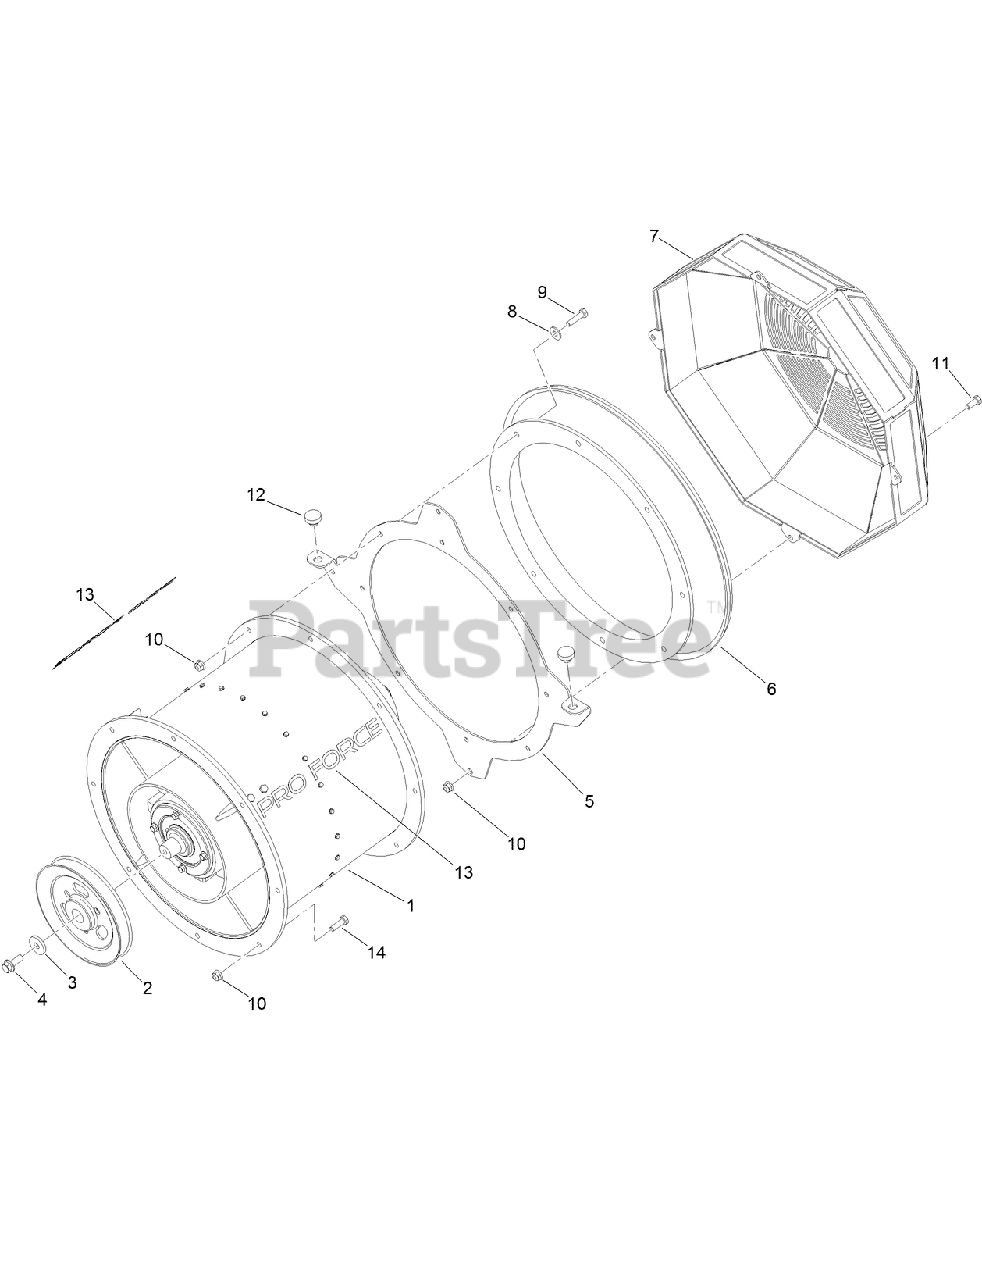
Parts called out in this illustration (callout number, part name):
1	TURBINE ASM
2	PULLEY
3	WASHER
4	SCREW-HHF
5	BRACKET-GUARD
6	BELL-INLET
7	GUARD-FAN
8	WASHER-FLAT
9	SCREW-HH
10	NUT-HF, NI
11	SCREW-HH
12	BUMPER-RUBBER
14	SCREW-HH
